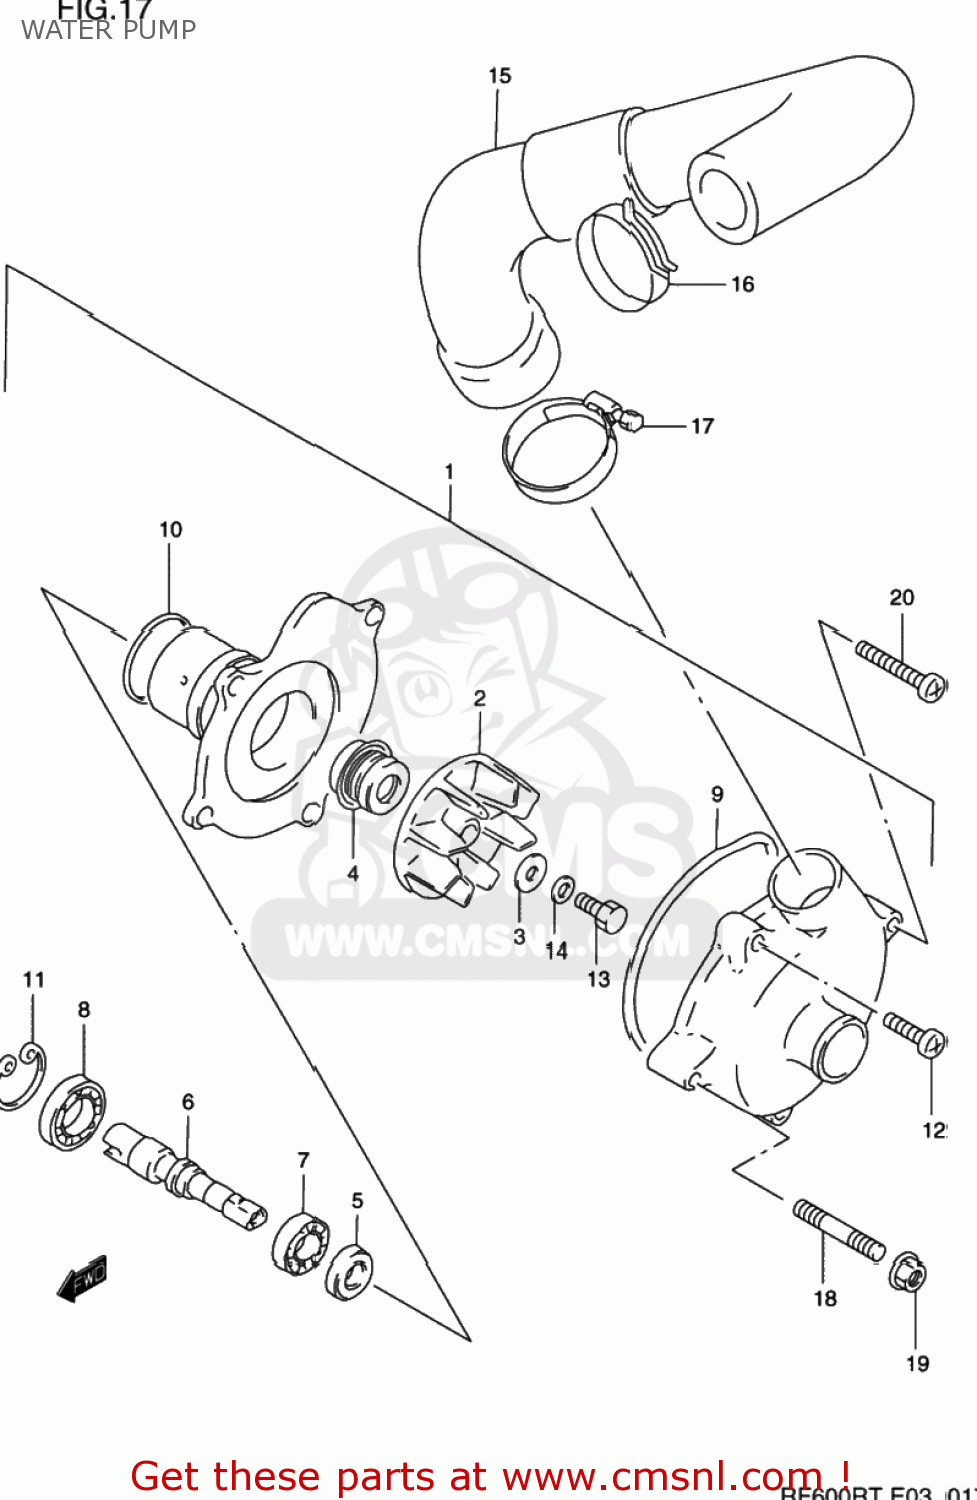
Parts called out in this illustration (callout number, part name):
1	PUMP ASSY,WATER
2	IMPELLER
3	GASKET(6X15X2.2) (NAS)
4	SEAL,MECHANICAL
5	OILSEAL
6	SHAFT
7	BEARING
8	BEARING(12X28X8)
9	O RING
10	O RING,WATER PUMP HOLDER
11	CIRCLIP
12	SCREW 6X16
13	BOLT(6X13)
14	WASHER
15	HOSE,WATER PUMP OUTLET
16	CLAMP
17	CLAMP
18	BOLT,STUD
19	NUT
20	SCREW
